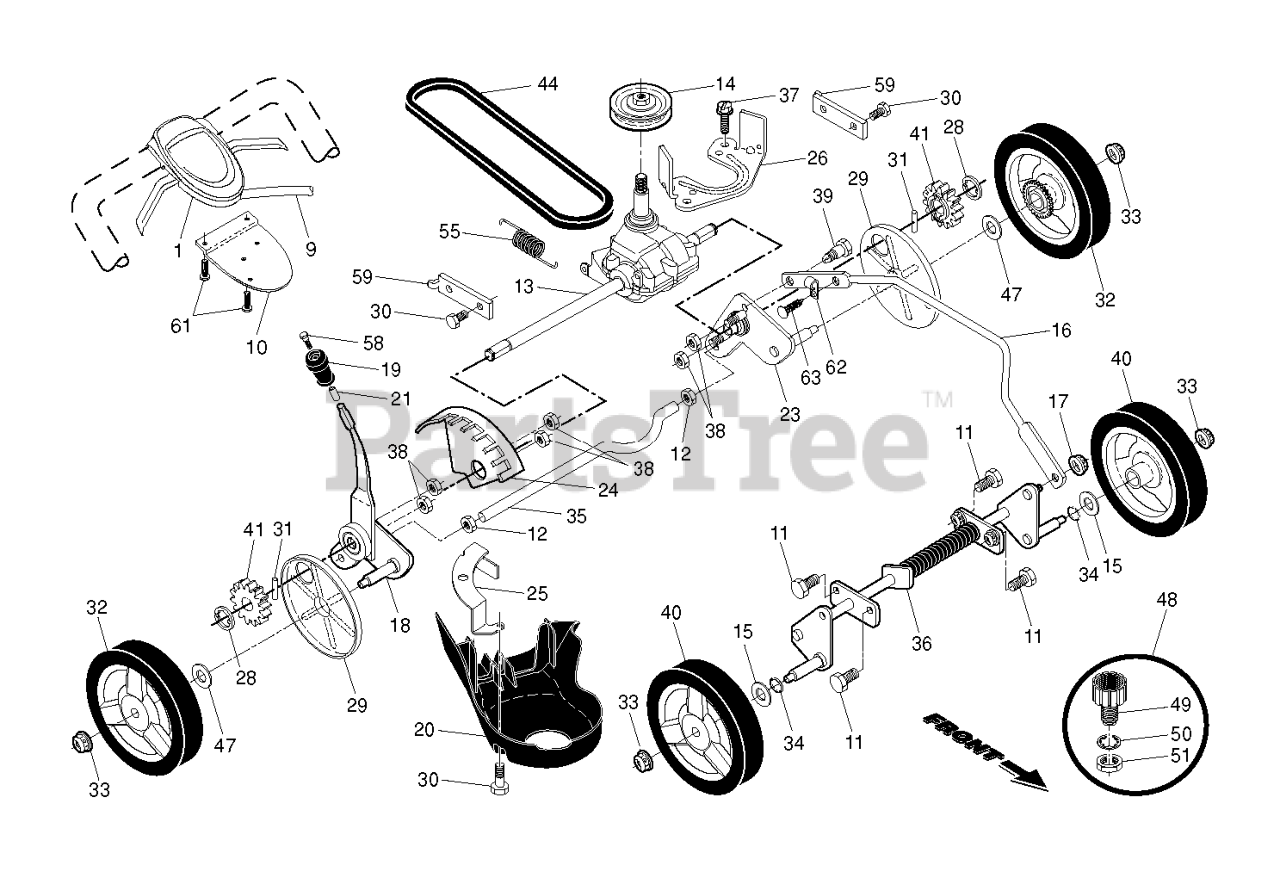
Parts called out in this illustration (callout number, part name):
1	RP CONTROL AW2 22+RGD KH GY/BL
9	CABLE.CONTROL.22RGD.GEN2
10	BRACKET.DRIVE.CONTR.GEN2.BLACK
12	NUT.HEX.1/2-20
13	RP TRANSMISSION.22+.RGD.AW2/
15	WASHER.FLAT.1/2
16	ROD.CONNECTING.RGD.22+.HW.BLAC
17	NUT.LOCK.5/16-18
18	KIT.SELECTOR.ASM.437869
19	KNOB.SEL.SPRING.22+.SP.RIB.BLK
20	COVER.BELT.22.RGD
21	SCREW.PLASTIC.ANCHOR.5/16
23	ADJUSTER.ARM.ASM.AX.RT.SP.ZC
24	BRACKET.WHL.ADJ.9.POS.W/PAD
25	BRACKET.DRIVE.COVER.RGD.BZP
26	BRACKET.TRANS.BELT.KEEPER.BZP
28	E-RING 7/16 RE
29	COVER.DUST.WHEEL
30	BOLT.5/16HEX.WHS.HD
31	PAWL, DRIVE
32	KIT.WHEEL.442789X460.8"
33	NUT.HEX.FLANGE.3/8-16.LO(3 2)
34	O-RING..070X.487.NEOPRENE
35	AXLE.REAR.RGD
36	RP AXLE.ASM.FRONT.RGD.ZINC
38	NUT.HEX.FLANGE.1/4
39	SHOULDER BOLT SEMI GIMLET PT.
40	WHEEL.8IN.H3SPK.ALPHA.
41	PINIION.14.TOOTH.RGD
44	BELT.DRIVE.RGD.PLUS
47	WASHER FLUT
48	KIT.WASH-OUT.PORT
49	FITTING, HOSE, WATER WASHOUT
50	WASHER.LOCK.INTERNAL.TOOTH
51	LOCKNUT.HEX.WITH.O-RING
58	SCREW.12-14X1.500
59	BRACKET.SUPPORT.22+.RWGD.BZP
61	SCREW, PHILLIPS HEAD 10 X 5/8
62	CLIP.CABLE.BLK
63	FASTENER.PUSH.O.250X0.783
